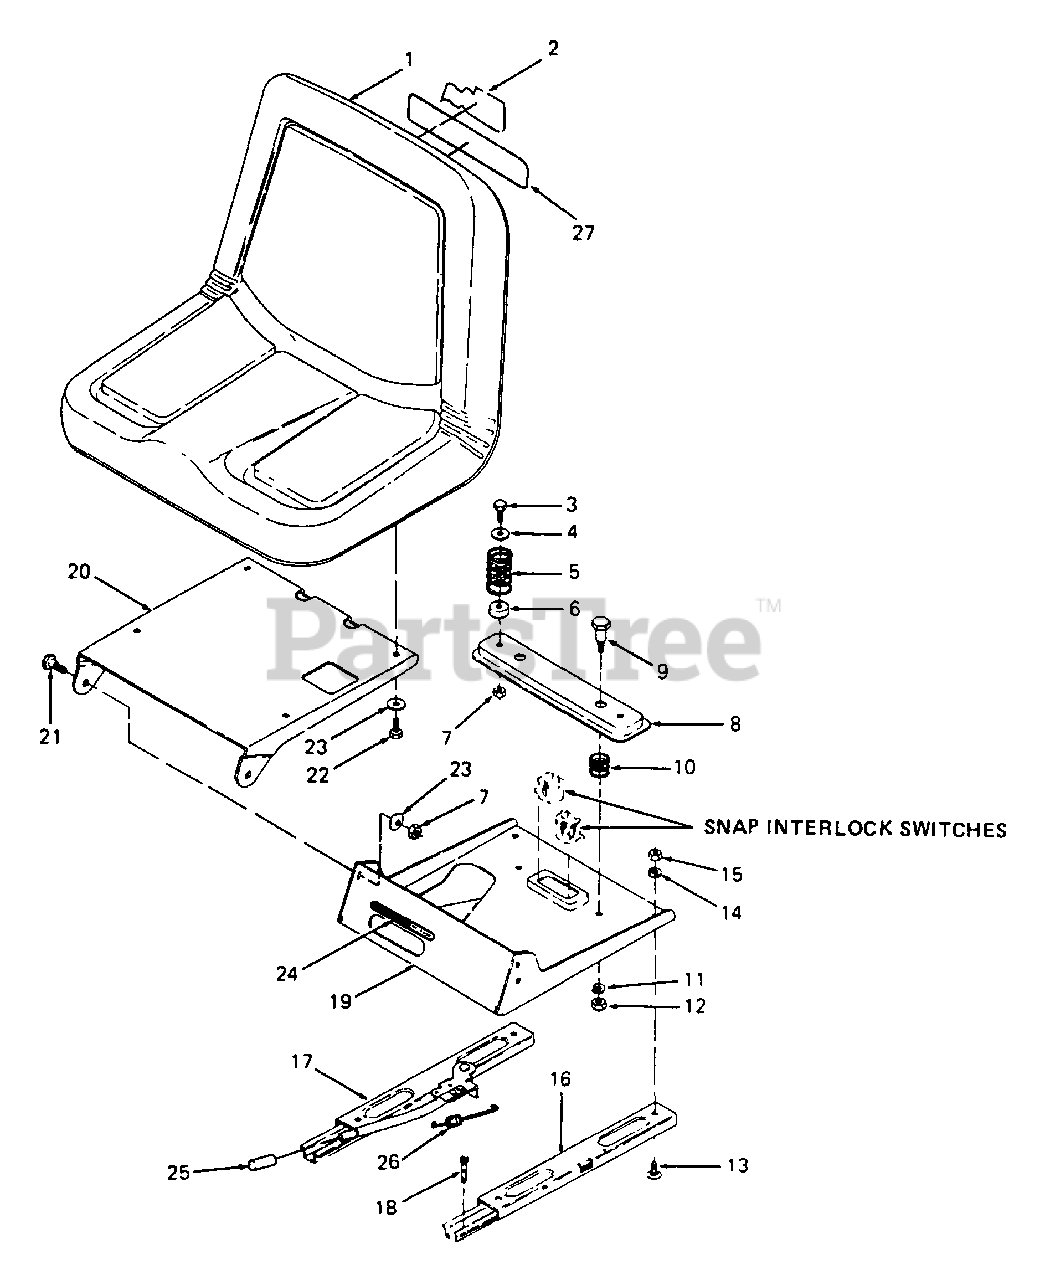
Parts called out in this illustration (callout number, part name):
1	Seat
2	Graphic, Made in USA
3	Screw, Hex Cap, 5/16-18 x .88 Lg GR5
4	Washer, Flat, .344 x .875 x .06 Thk
5	Spring, Comp, 1.28 OD x 2.18 Lg
6	Bushing, .930 OD x .50 Lg
7	Nut, Hex Center Lock, 5/16-18 GR5
10	Spring, Comp, 1.00 OD x .86 Lg
11	Washer, Lock, 3/8
12	Nut, Hex, 3/8-16 GR5
13	Bolt, Sht Nk Carriage, 5/16-18 x .62 Lg
14	Washer, Lock, 5/16
15	Nut, Hex, 5/16-18 GR5
16	Slide, Seat - LH
17	Adjuster, Manual Seat - RH
18	Screw, Socket Hd Cap, 5/16-18 x 1.00 Lg
22	Screw, Hex Cap, 5/16-18 x .75 Lg GR5
23	Washer, Bell, .345 x .88 x .060 Thk
24	Label, Seat Adjustment
25	Cover, Handle
27	Graphic, Seat Back Script
